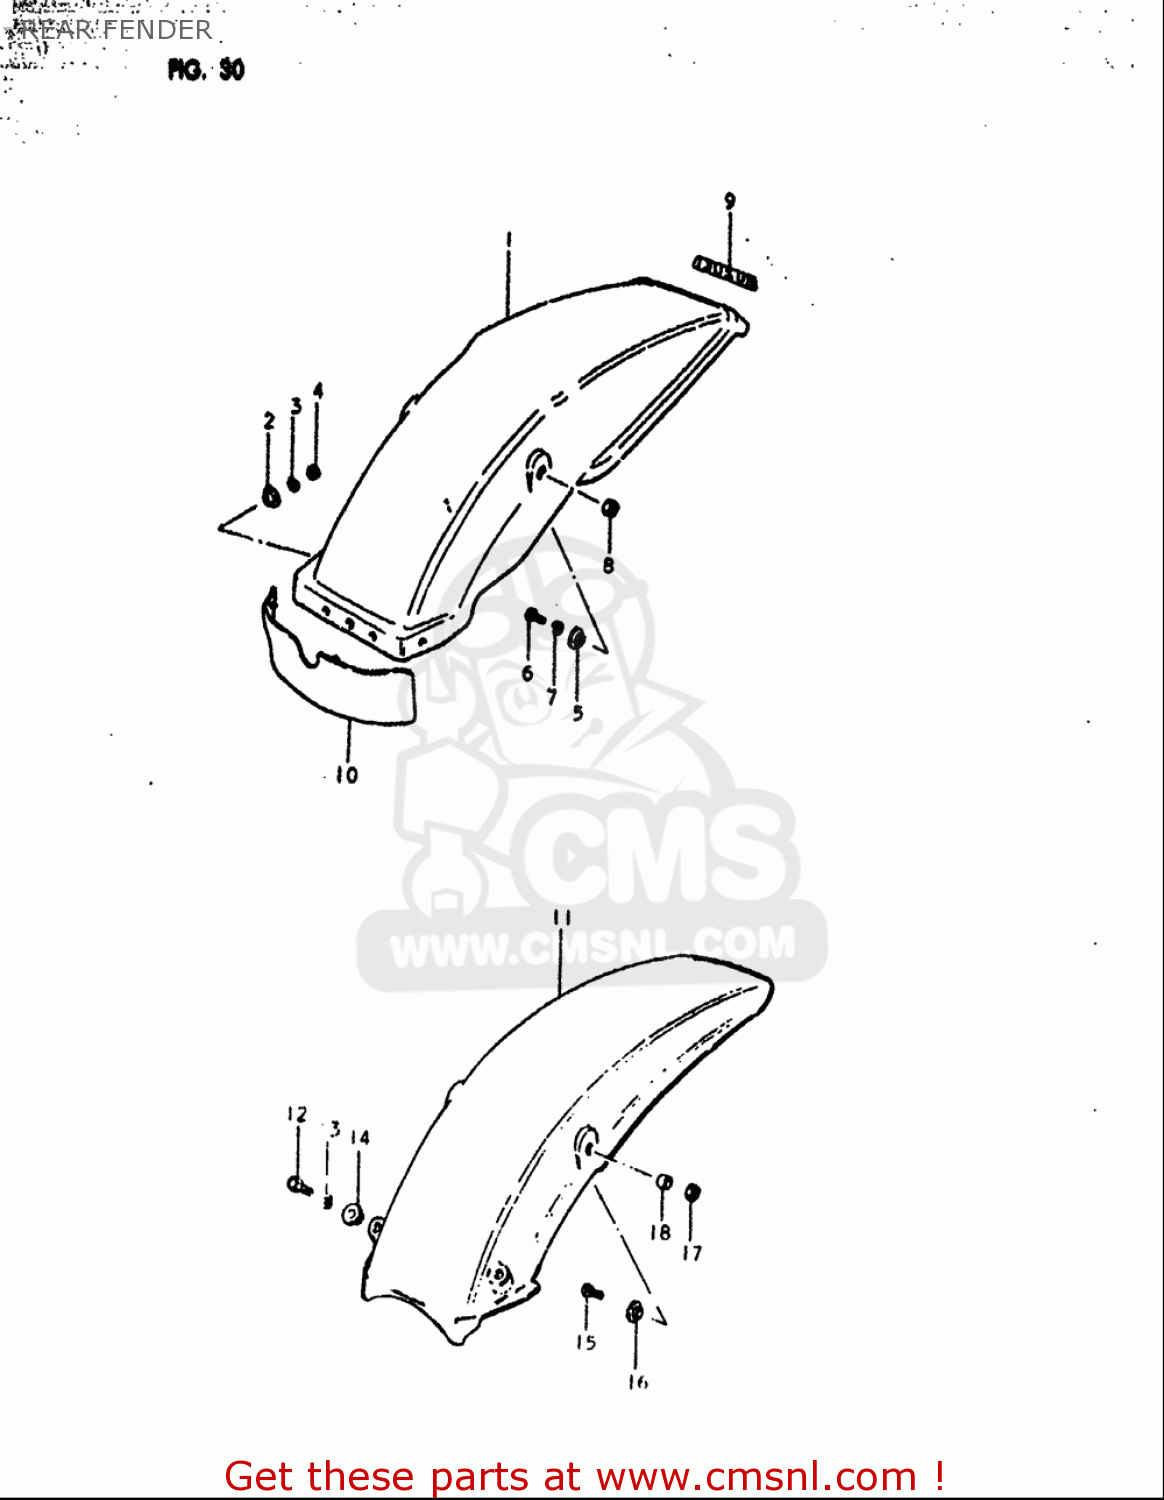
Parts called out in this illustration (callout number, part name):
2	WASHER
3	WASHER,LOCK
4	NUT
5	WASHER
6	BOLT
7	WASHER,LOCK
8	NUT
12	BOLT
13	WASHER,LOCK
14	WASHER
15	SCREW
16	WASHER(6.5X20X1.2)
17	NUT 6MM
